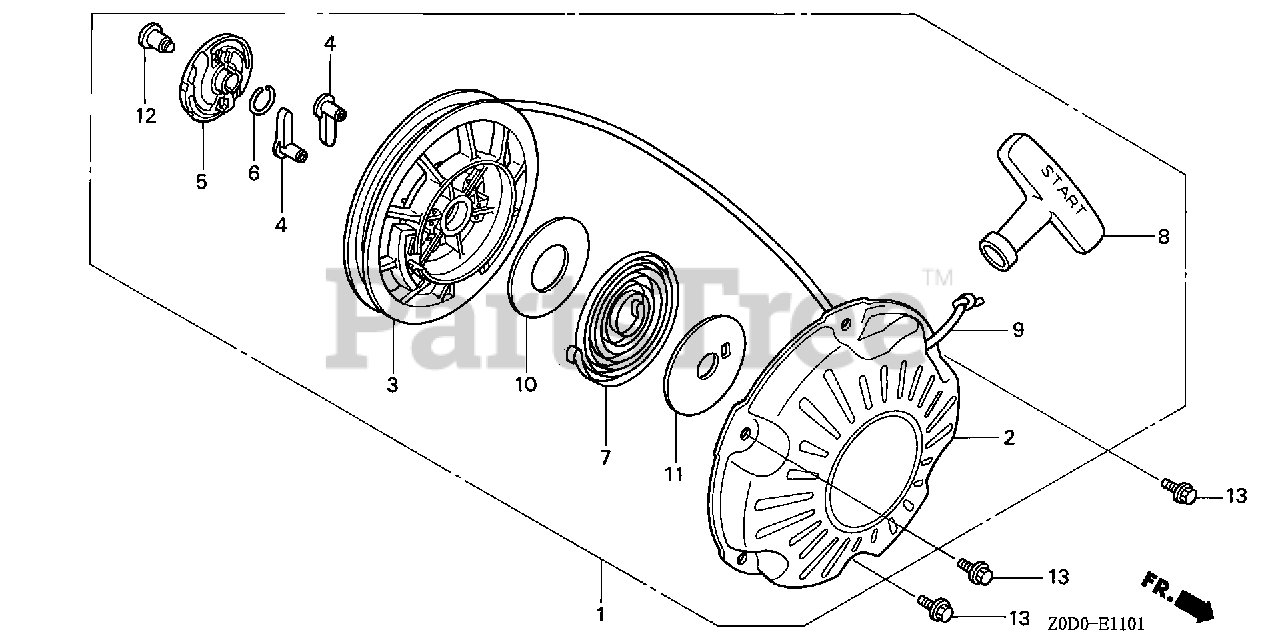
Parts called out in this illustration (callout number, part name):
1	STARTER ASSY., RECOIL *NH1* (BLACK)
2	CASE, RECOIL STARTER *NH1* (BLACK)
3	REEL, RECOIL STARTER
4	RATCHET, STARTER
5	GUIDE, RATCHET
6	SPRING, FRICTION
7	SPRING, RECOIL STARTER
8	GRIP, STARTER
8	KNOB, RECOIL SRARTER
9	ROPE, RECOIL STARTER
10	PLATE, SIDE
11	PLATE, SLIDE
12	SCREW, SETTING
13	BOLT, FLANGE (6X8)
